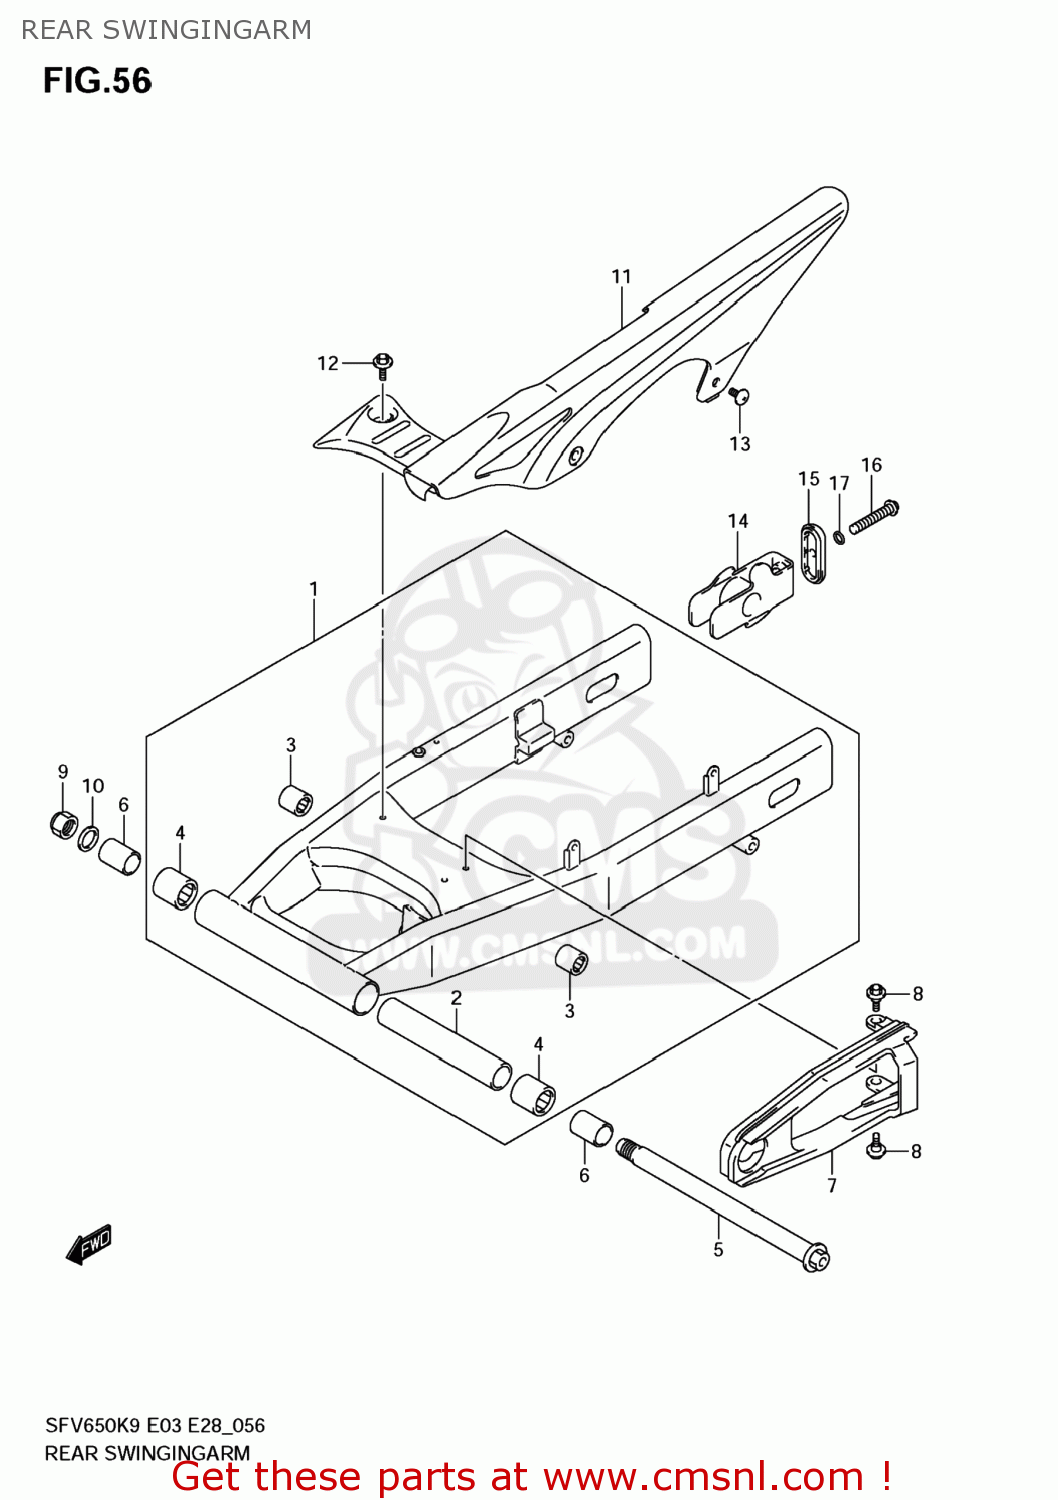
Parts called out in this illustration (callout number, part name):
1	SWINGINGARM ASSY,RR
2	SPACER,RR SWGARM PIVOT CTR
3	BEARING(17X24X25)
4	BEARING(25X33X35)
5	SHAFT,RR SWINGINGARM PIVOT
6	SPACER,RR SWGARM PIVOT
7	BUFFER,CHAIN TOUCH DEFENSE
8	BOLT(6X17.8)
9	NUT
10	WASHER(18.5X28X2.6)
11	CASE,CHAIN
12	BOLT(6X16)
13	SCREW(6X16)
14	ADJUSTER,CHAIN
15	PLATE,CHAIN ADJUSTER GUIDE
16	BOLT(8X50)
17	WASHER
